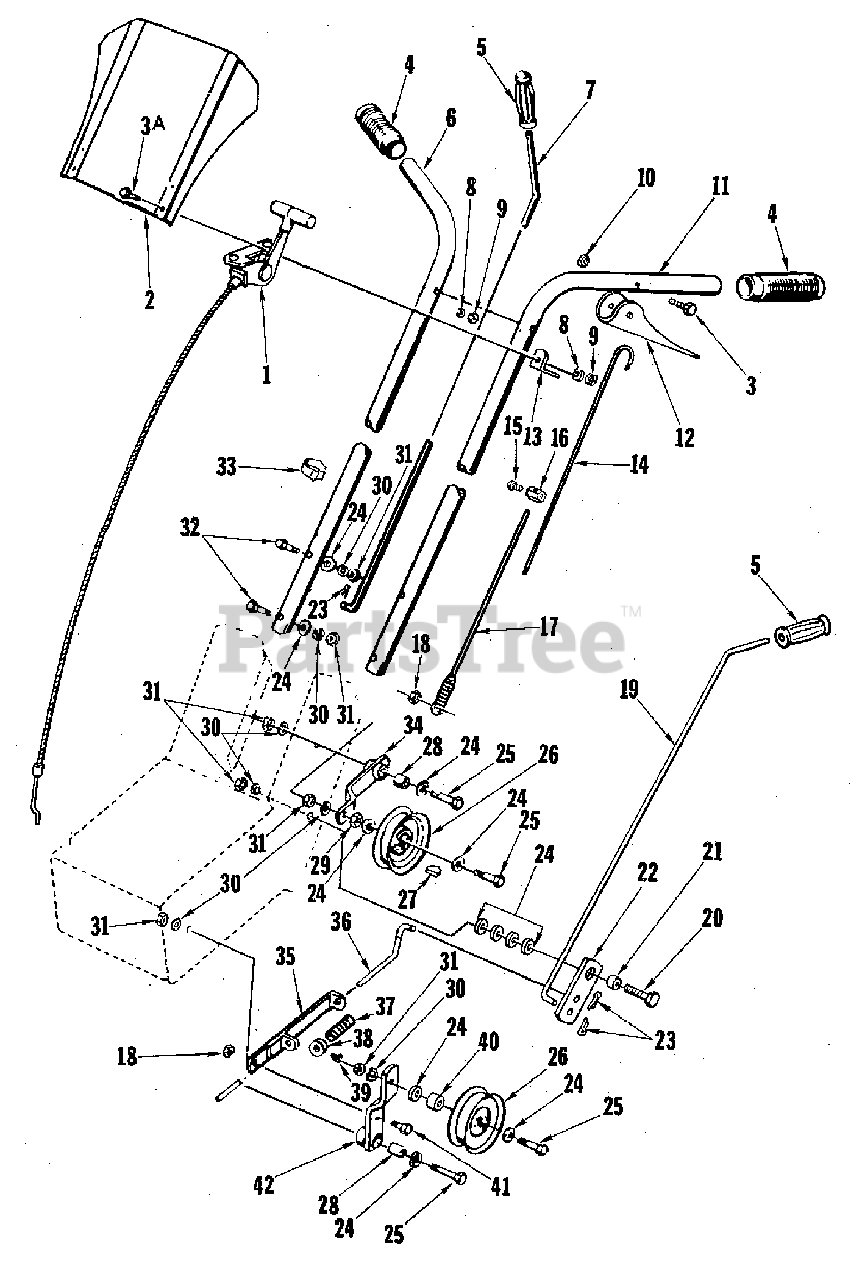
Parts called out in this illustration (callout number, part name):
1	THROTTLE CONTROL ASSEMBLY
2	HOUSING ASSEMBLY
3	SCREW, Hex Head, 1/4-20 x 1-1/2
3A	SCREW, Hex Head, 1/4-20 x 1/2
6	HANDLE, Right
7	REVERSE ROD ASSEMBLY
7	PIN, Roll, 3/32 x 5/8
8	WASHER, Lock, 1/4
9	NUT, Hex, 1/4-20
10	NUT, Hex, 1/4-20
11	HANDLE, Left
12	GRIP, Clutch
13	SPRING, Clip
14	EXTENSION, Spring
15	SCREW, Round Head, 10-24 x 3/8
17	SPRING ASSEMBLY
18	NUT, Hex, 3/8-16
23	PIN, Cotter, 3/32 x 3/4
24	WASHER, Plain, 3/8"
25	SCREW, Hex Head, 3/8-16 x 1-3/4
26	PULLEY, Idler
28	RACE, Inner Bearing
29	NUT, Hex, 3/8-16
30	WASHER, Lock, 3/8"
31	NUT, Hex, 3/8-16
32	SCREW, Hex Head, 3/8-16 x 2
34	LEVER ASSEMBLY, Idler
35	GUIDE ASSEMBLY, Clutch Rod
36	ROD, Clutch Rotor
39	SCREW, Set, Square Head, 1/4-20 x 3/8
41	SCREW, Hex Head, 3/8-16 x 7/8
42	LEVER ASSEMBLY, idler
